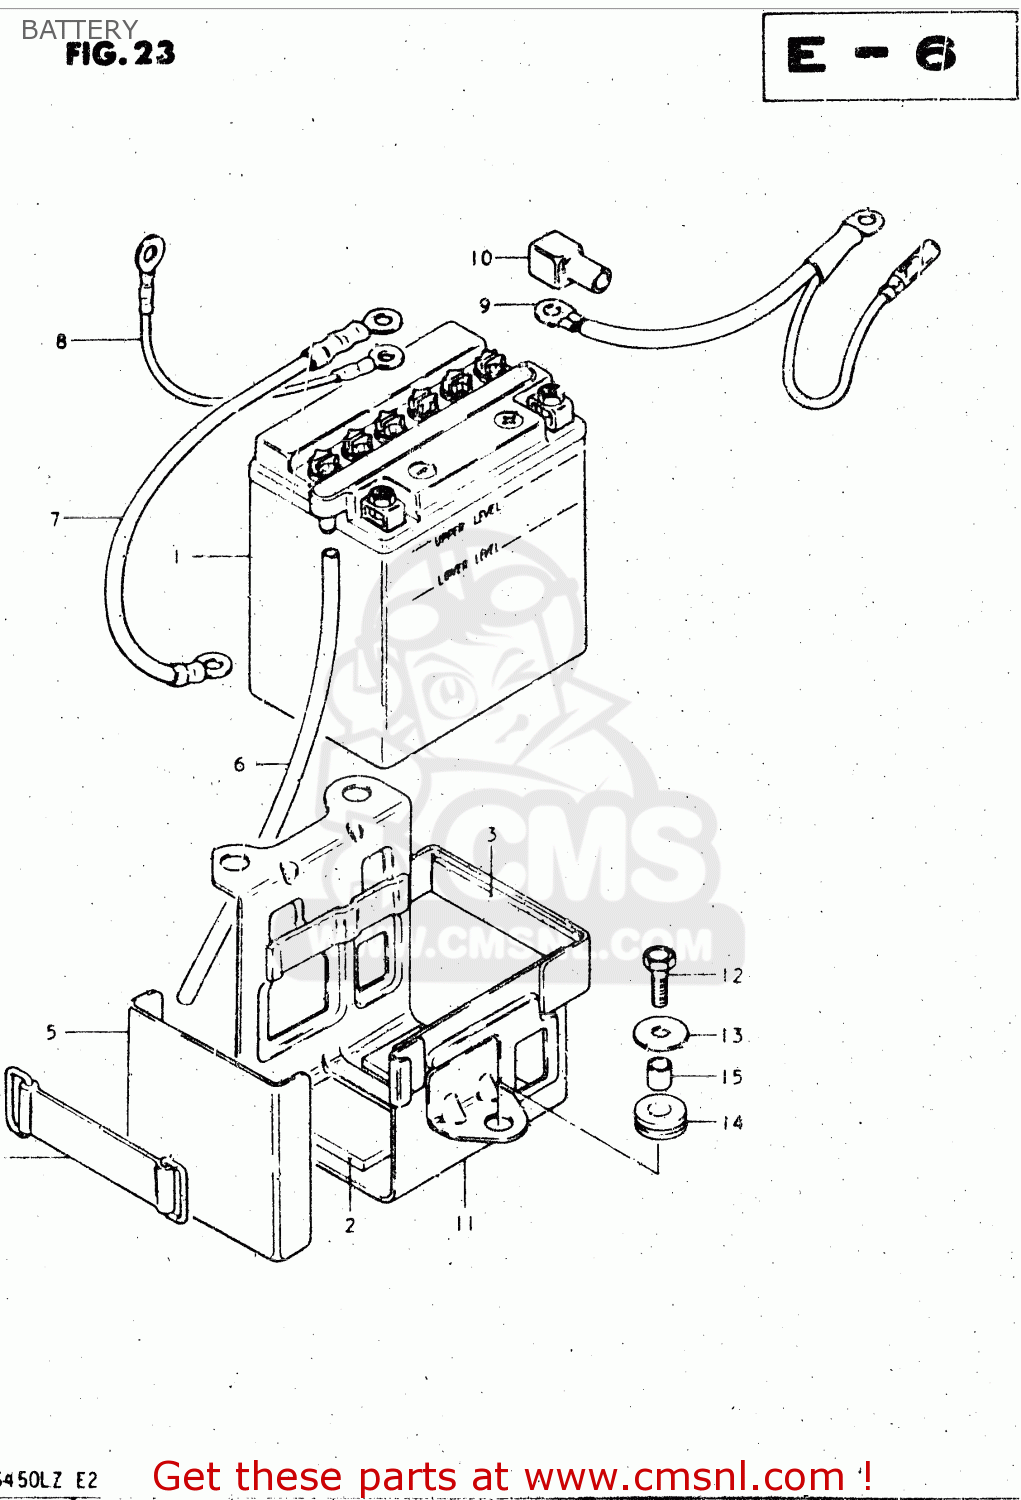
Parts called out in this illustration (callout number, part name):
1	BATTERY ASSY (12V)
2	CUSHION,BATTERY
3	PROTECTOR,20X9
4	BAND
5	COVER,BATTERY
6	HOSE,BATTERY EXHAUST
7	CORD,BATTERY MINUS
8	WIRE
9	WIRE,BATTERY PLUS
10	CAP,TERMINAL
11	HOLDER,BATTERY
12	BOLT
13	WASHER
14	CUSHION
15	SPACER (6.1X9X9)
